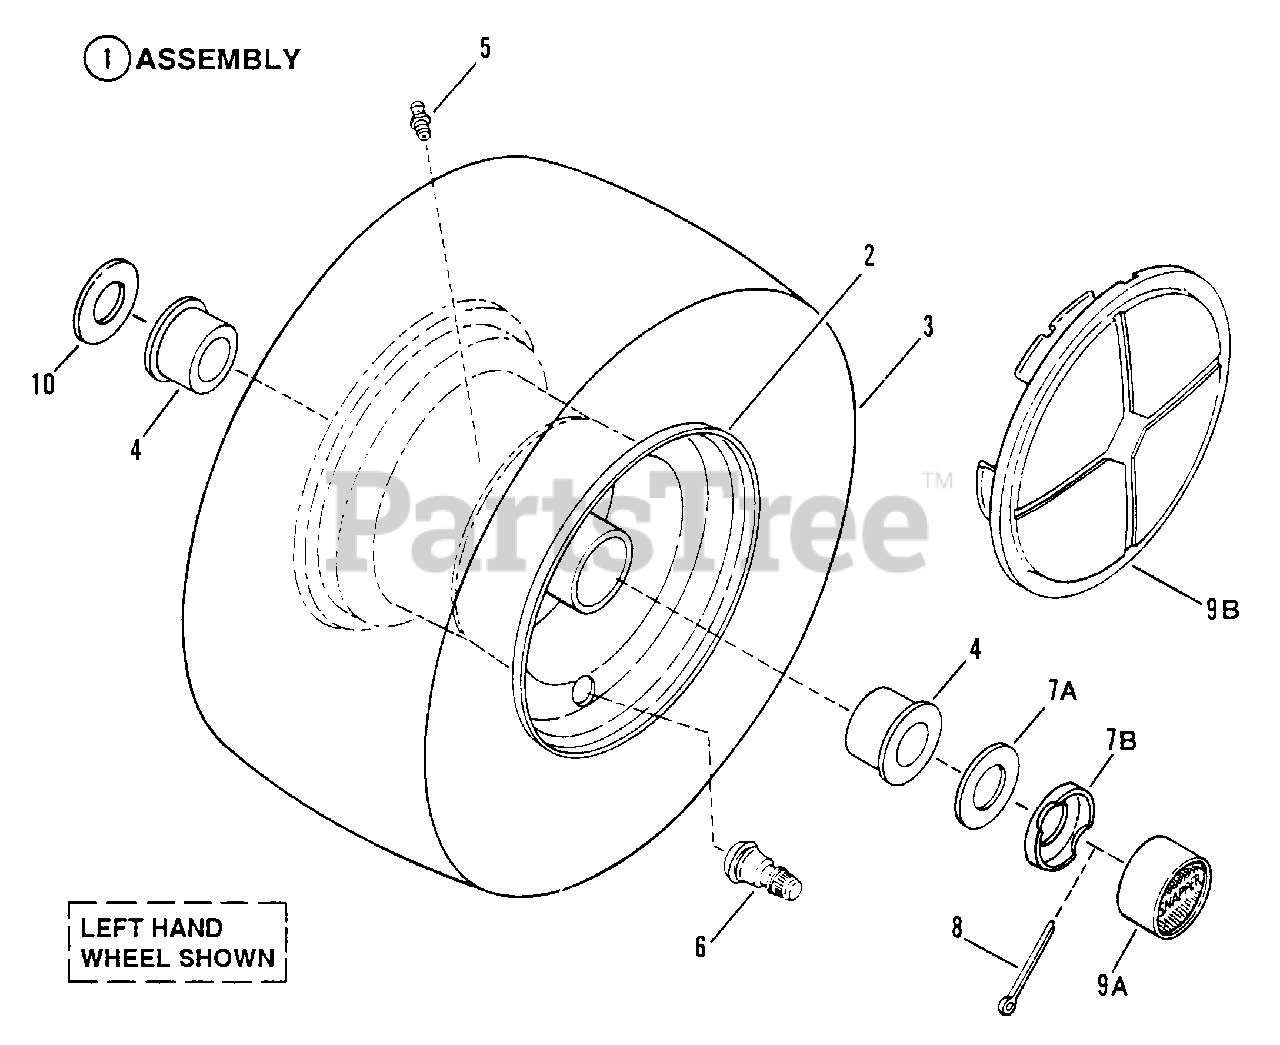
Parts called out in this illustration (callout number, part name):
1	ASSEMBLY, Front Tire & Rim
2	RIM, 5.50 x 4.00
3	TIRE, 13 x 5.00
3	TIRE, 15 x 6.00
4	BEARING, Wheel
5	FITTING, Lube 1/4-28 Tapered Thread
6	VALVE, Air (Snap-in)
7A	WASHER, 49/64 I.D. x 1-1/2" O.D.
7B	RETAINER, Hub-Cap
8	COTTER-PIN
9A	HUB-CAP
9B	WHEEL-COVER
10	WASHER, 25/32 I.D. x 1-1/2" O.D.
